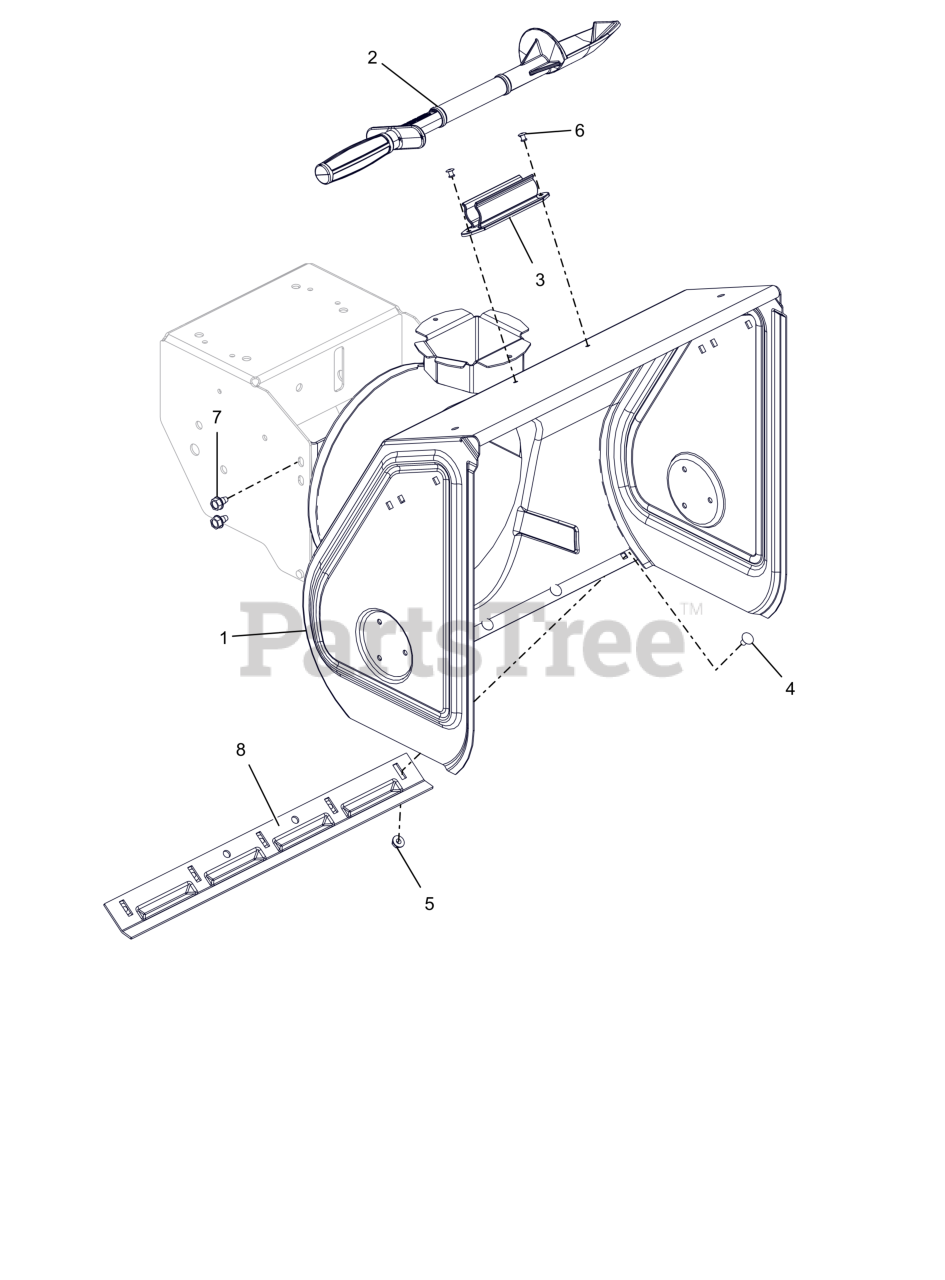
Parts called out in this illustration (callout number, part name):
1	BLOWER HOUSING W/DECAL 20"
2	DEVICE, SNOW CLEAN OUT
3	MOUNT, SNOW CLEAN OUT
4	BLT, RHSSN.25-20X.500 G5 ZCC
5	NUT-LK-CTR-FLG .25-20 ZC120
6	RVT, POP .1875 ZCC
7	SCR,TAP .312-18X.50 HWH TR ZCC
8	BLADE, SCRAPER (BLACK)
